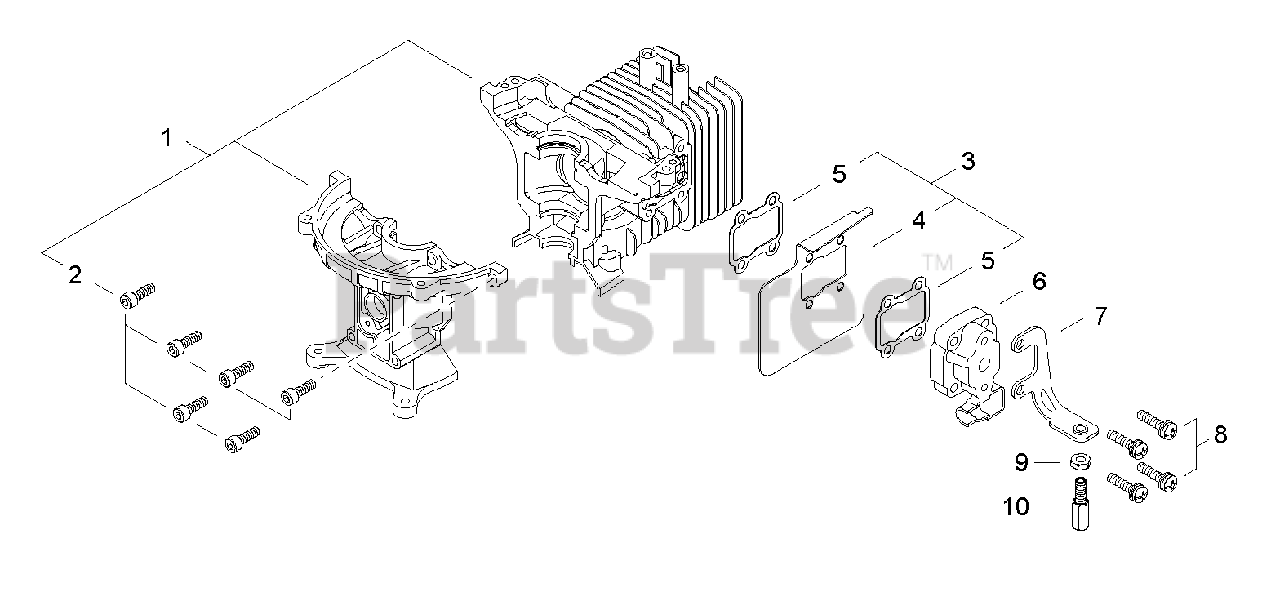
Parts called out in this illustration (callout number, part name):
1	CYLINDER & CRANKCASE ASSY
2	BOLT 5×16
3	SHIELD ASSY, INTAKE HEAT
4	HEAT SHIELD, INTAKE
5	GASKET, EXHAUST
6	INSULATOR WITH REED VALVE
7	BRACKET, THROTTLE CABLE
8	SCREW M5×22
9	NUT, ADJUSTER LOCK M6
10	ADJUSTER, THROTTLE CABLE
